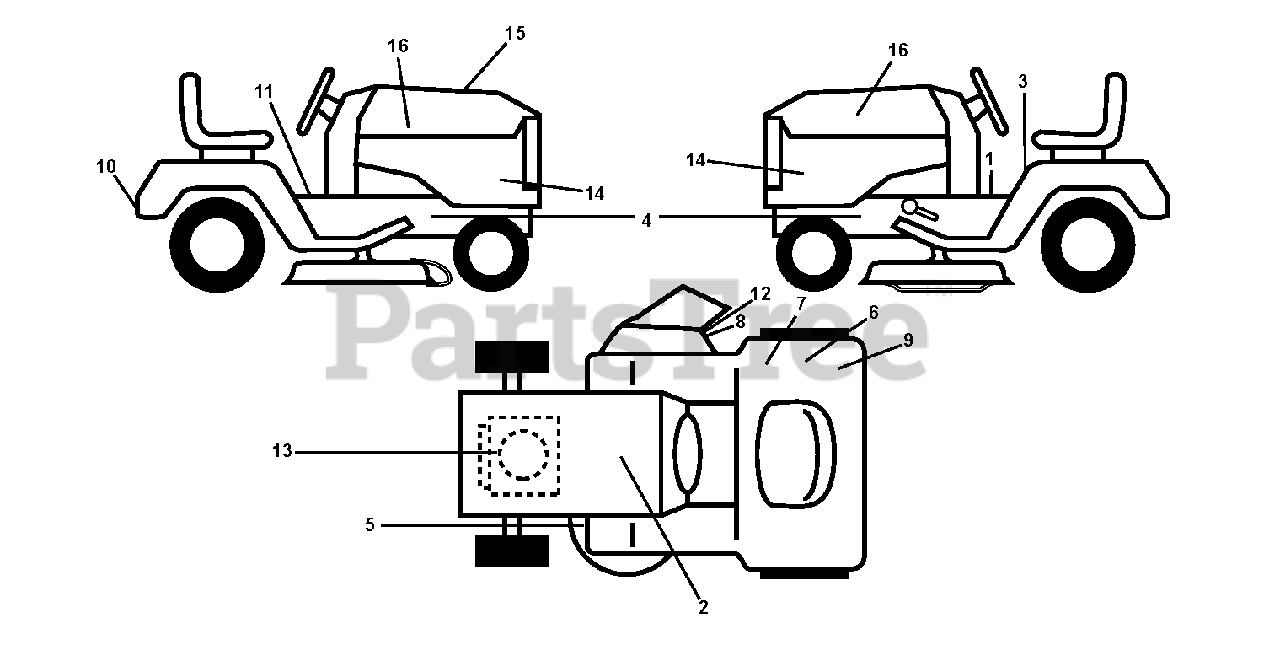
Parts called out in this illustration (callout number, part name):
1	DECAL PARK BRAKE
2	DECAL BTRY SYMBOLS
3	LABEL
5	DECAL V BELT SCHEMATIC
6	DECAL
7	DECAL 80 DBA
8	DECAL, DEFLECT WARNING
9	DECAL
10	DECAL
11	DECAL
12	DECAL.INTERNATIONL.CUTFINGER
13	DECAL
16	RP.DECAL.BADGE.170MM.TEXTLOGO
